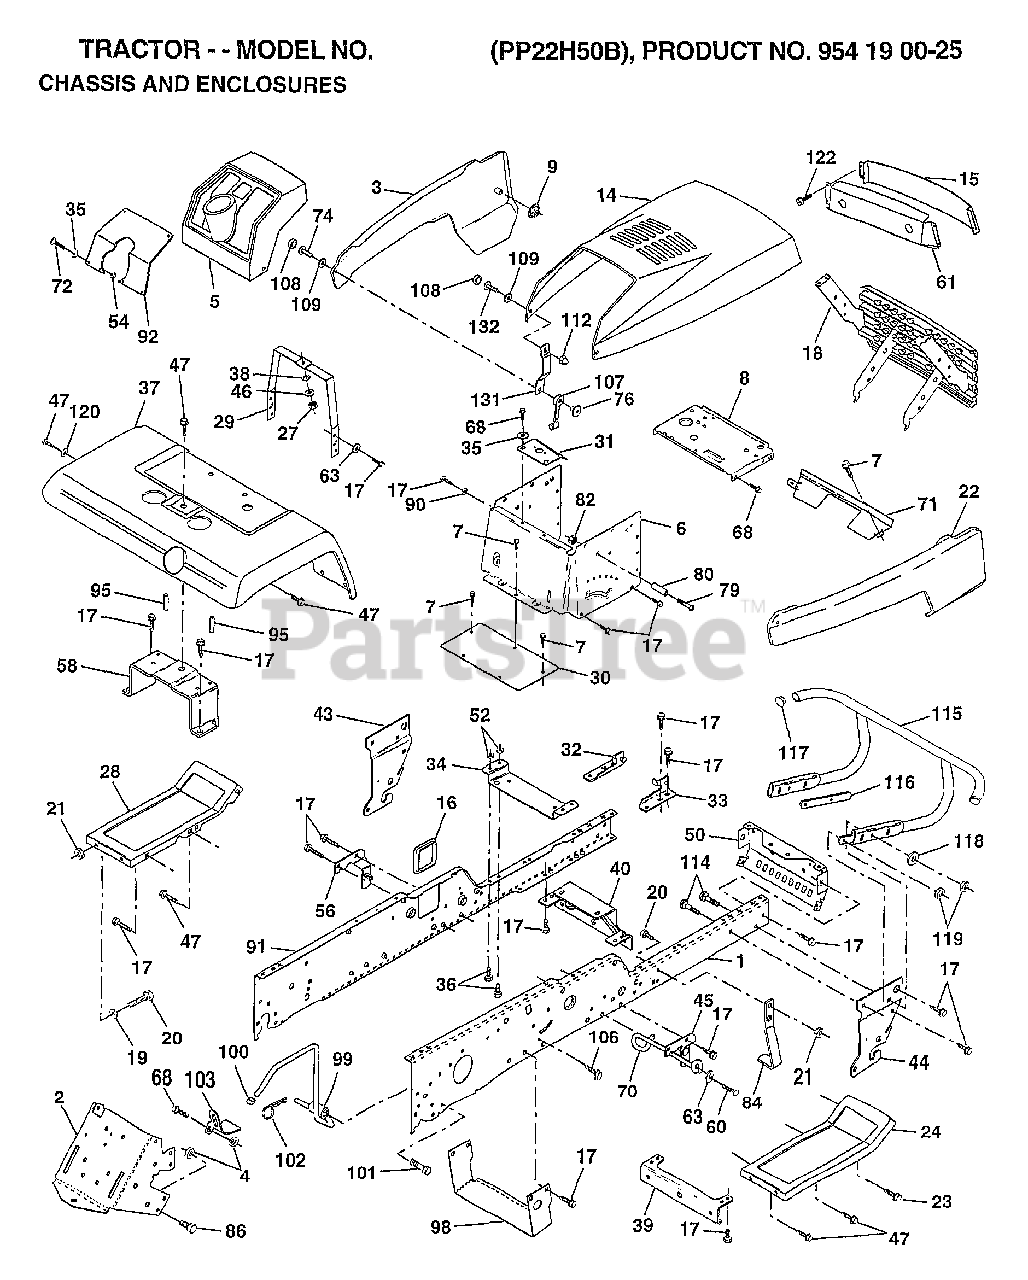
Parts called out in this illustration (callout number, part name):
1	"RAIL,FRAME RH"
2	DRAWBAR GT
3	"PANEL ASM-SIDE,LH"
4	NUT.7/16
5	DASHBOARD BLACK
6	DASH LOWER
7	SCREW
8	SUPPORT.DASH.BTRY
9	PAL NUT LT
14	"HOOD, YARD PRO"
15	LENS.BAR.CLEAR
16	COVER ACCESS
17	SCREW
19	WASHER
20	BOLT
22	"PANEL ASM SIDE,RH"
23	SCREW GTV
24	FOOTREST.RH.LT/GT
28	FOOTREST.LH.LT/GT
29	DASH.SUPT.YP/HUSQ
30	SADDLE.HYDRO.95
31	BRKT SUPT 1-PC VG
32	BRACKET ASM FRAME
33	BRACKET ASM FRAME
34	BRACKET.ENG.SUPT.
35	WASHER
36	BOLT
37	FENDER.PNT.
38	LOCKWASHER
39	BRACKET.AXLE.FRT.
40	"BRKT SUPPORT,AXLE"
43	BRACKET.SUS.FT.LH
44	BRACKET.SUS.FT.RH
45	BRACKET.SUSP.RH.
46	WASHER PM
47	SCREW LT
50	"BRKT CHASSIS,FRNT"
56	BRACKET.SUSP.LH.
58	BRKT.ASM.FENDER
60	SCREW
61	BEZEL.ASM.
63	WASHER
68	SCREW LT
70	GUIDE.BELT.MID.SP
72	SCREW
74	SCREW
76	WELDNUT
79	SCREW
80	SPACER LT
84	STOP.OVER.CENTER
86	BOLT
90	LOCKWASHER
91	"RAIL FRAME,LH"
92	PLATE, SILKSCREEN DASH
95	NUT-PUSH YT
98	BRACKET SKID CHAS
99	ROD BYPASS
101	SCREW LT
102	RETAINER M
103	LOCK BYPASS BRKT
107	HOOD LATCH T
108	SNAP CAP LT
109	WASHER LT
112	ACORN NUT RB
114	BOLT.3/8-14X1.25
115	BUMPER.ASM
116	BRACKET.EXT.BUMP.
117	PLUG.PLASTIC
118	WASHER
120	WASHER HYT
122	SCREW.HEX.WS.HD
131	BKT.SPT.HOOD/PANL
132	SCREW.10-24X3/8.
